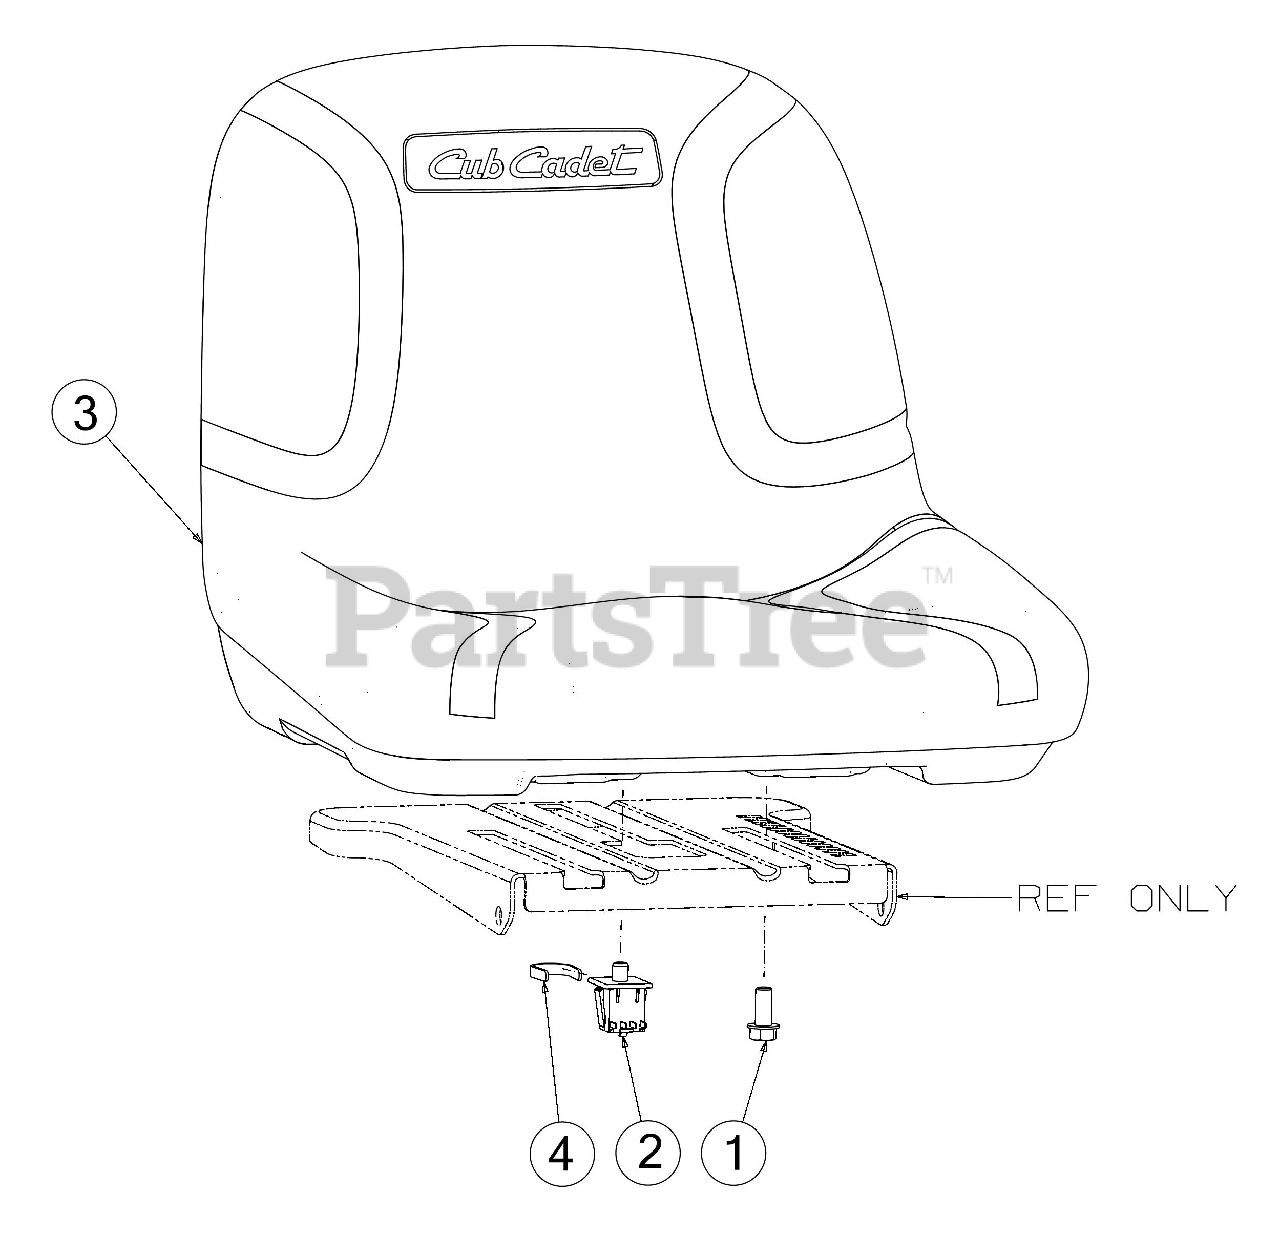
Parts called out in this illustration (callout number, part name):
1	SCREW 3/8-16 X .875 GR5
2	SEAT SWITCH
3	HIGH BACK SEAT (CUB)
4	RETAINING CLIP
